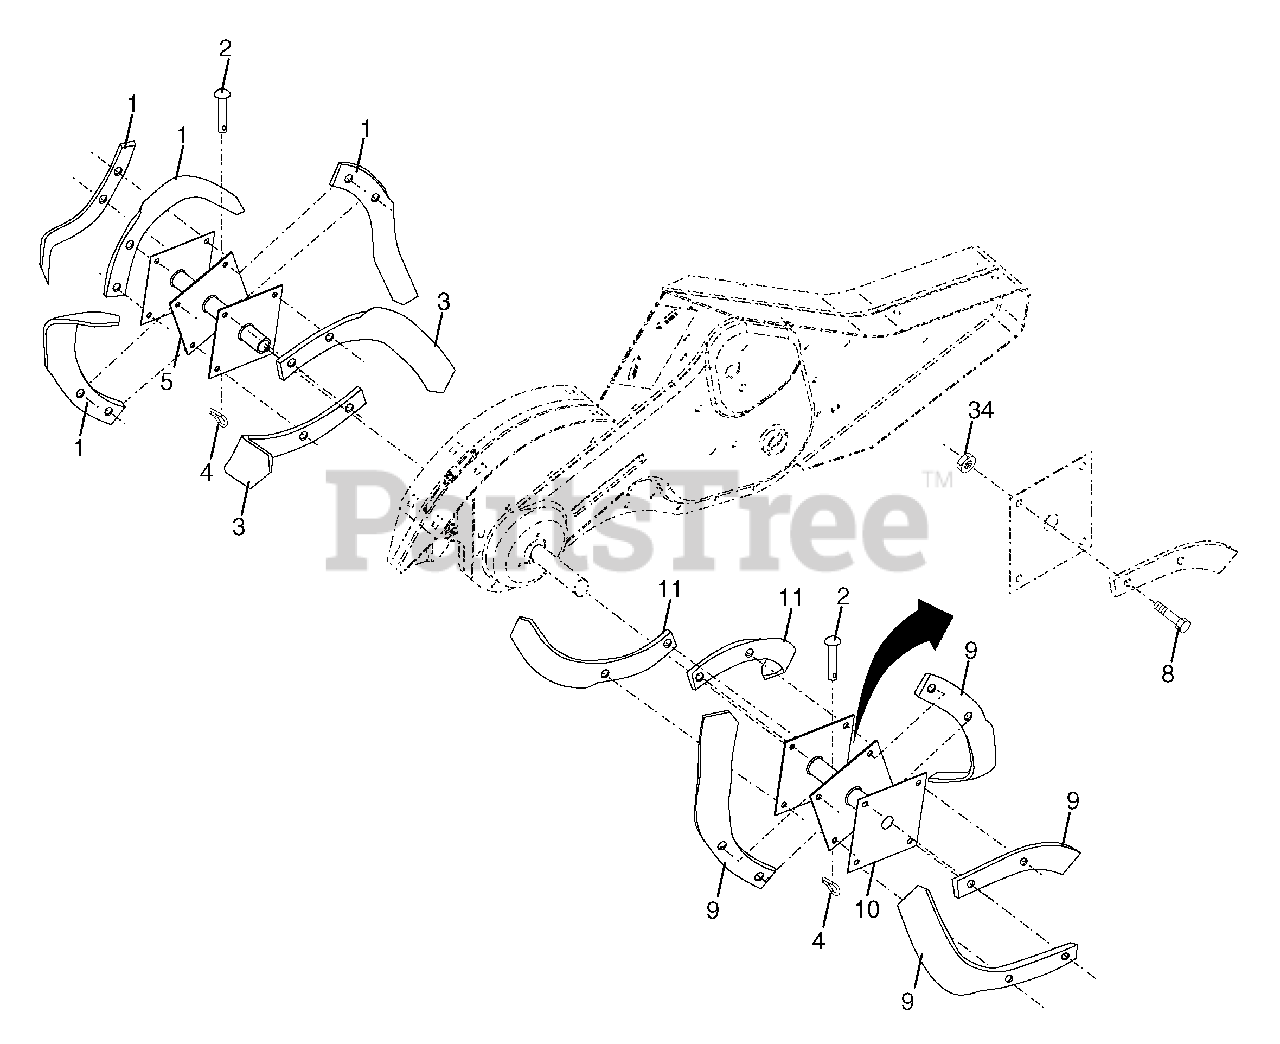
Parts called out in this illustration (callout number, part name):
1	Tine, Outer, LH
2	Clevis Pin
3	Tine, Inner, LH
4	Retainer, Spring, Zinc-Plated
5	Assembly, Hub and Plate, LH
8	Bolt, Hex Head 3/8-24 x 1
9	Tine, Outer, RH
10	Assembly, Hub and Plate, RH
11	Tine, Inner, RH
34	Nut, Hex, Crownlock 3/8-24
